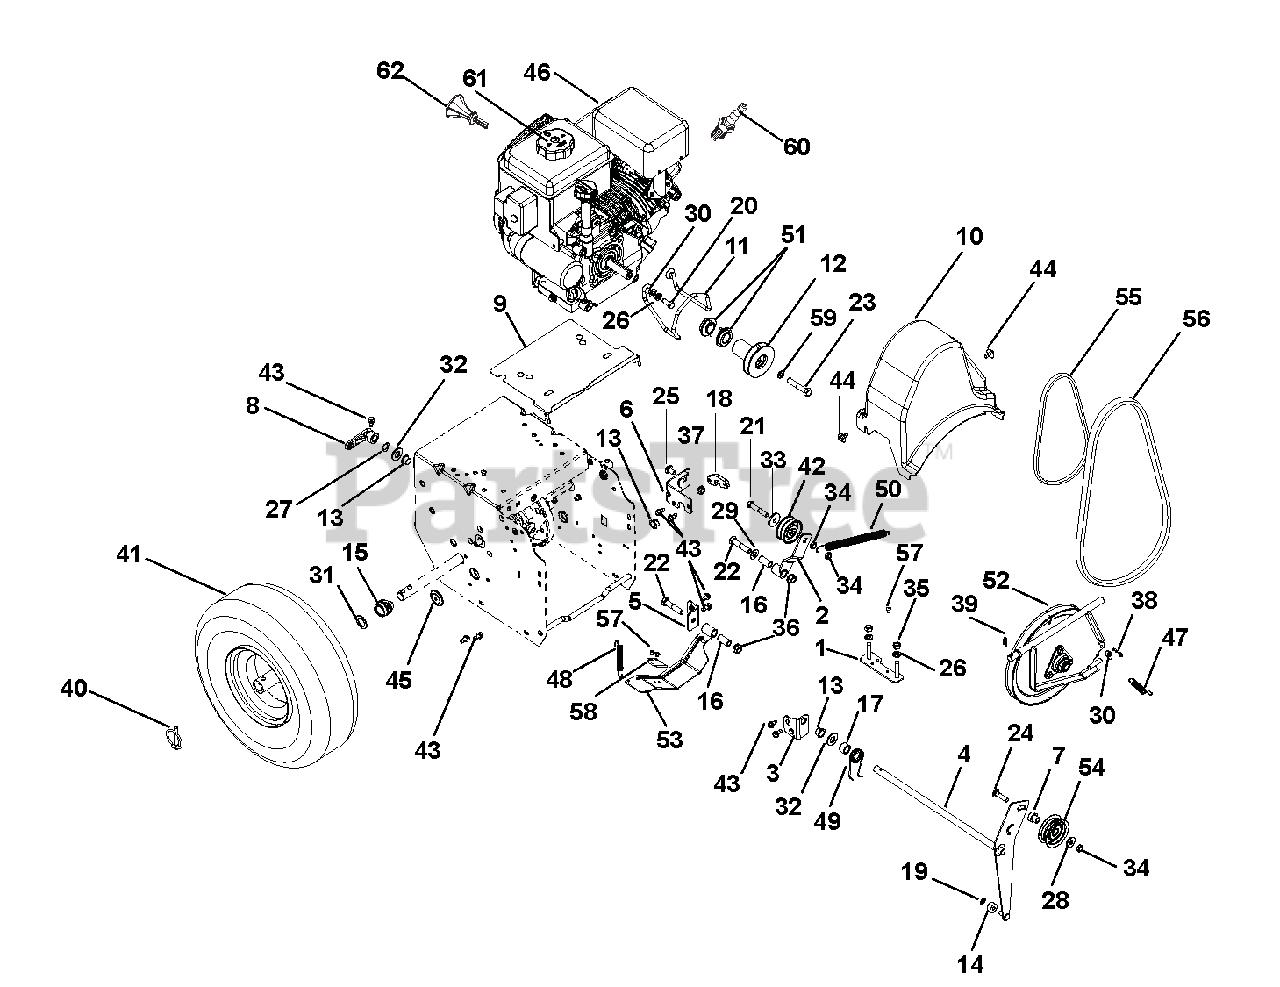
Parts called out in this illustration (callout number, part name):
1	STRAP, ENGINE BOLT-WELDMENT
2	WELDMENT, TRACTION IDLER ARM
3	BRACKET, MOUNT - IDLER ARM
4	WELDMENT, ATTACHMENT IDLER ARM
5	BRACKET, MOUNT - BRAKE
6	WELDMENT, FRAME BRACKET
7	SPCR, BRG .315X.50X.688X.281
8	ARM, CLUTCH - ATTACHMENT
9	BAFFLE,ENGINE,SMALL BLOCK
10	COVER, COMPACT BELT
11	FINGER, BELT
11	BELT FINGER
12	SHEAVE, AUGER - COMPACT
12	SHEAVE, ATTACHMENT DRIVE
13	BUSHING, POLYLINER-.50 SPLIT
14	BSHG,SLV .265 X .625 X .375
15	BSHG .75X1.125X.65
16	BSHG-SLV .385X.500X1.045
17	BSHG-SLV .510X.751X.475
18	SPACER, SWING GATE
19	RG-RTNG-EXT .250X.010
20	BLT-HEX .31-24X.75 YWZC GR5
21	@BLT-HEX .31-18X1.75 GR5 YWZC
22	@BLT-HEX .38-16X1.75 GR5 YWZC
23	BLT-HEX .38-24X2.0 YWZC
24	BLT-RDHDSQSHNK.31-18X1.13 G5YZ
25	@BLT-RHDSSQNK .31-18X.62 G5YZ
26	WSHR-LK .312X.097 HVY YWZC
27	WSHR-WAVE .50X.75X.015 .13FRHT
28	@WSHR-FL-STL.38X.875X.083 YWZC
29	@WSHR-FL-STL.406X.812X.065 YWZ
30	@WSHR-FL-STL.344X.688X.065YWZC
31	WSHR-FL-STL.754X1.125X.062YWZC
31	BSHG-SLV .75X1.12X1.062 NYL BK
32	@WSHR-FL-STL.531X1.06X.095YWZC
33	WSHR-FL-STL .344X1.125X.135
34	@NUT-LK-CTR-JAM .31-18 YWZC
35	@NUT-HEX .31-18 YWZC
36	@NUT-LK-TOP-FLG .38-16 YWZC
37	@NUT-LK-TOP-FLG .31-18 YWZC
38	PIN-HAIR INT .08X.18X1.18 YWZC
39	CLIP, SPRING
40	PIN-LOK .31X1.75
41	TIRE/WHEEL, 15X5.00-6 K398A
41	TIRE/WHEEL, 13X4.10-6 K398A
41	TIRE, 13" K398A
41	TIRE, 15" K398A
42	IDLER,1.875" OD
43	SCR-TAP .25-20X.50 HWH TR YWZ
44	SCR-TAP .25-20X.50 LGHWH TR YZ
45	PLUG, HOLE - 1.00" FLEXTEMP
46	ENGINE,LCT STORMFORCE 208 120V
46	ENGINE,LCT STORMFORCE 136 120V
47	SPRING, EXT. .043X.438X1.64
48	SPRING-EXT .437 X .438 X 2.64
49	SG-TORS .075 X .955
50	SPRING, EXTENSION
51	TRACTION SHEAVE HALF
52	PLATE, SWING - ASSEMBLY
53	BRAKE ARM W/PAD
54	IDLER
55	V-BELT, 3L-WRAPPED
56	V-BELT, HA-RAW EDGE
57	RVT-POP .187 YZ
58	PAD, BRAKE
59	@WSHR-LK .38X.094 REG YWZC
60	PLUG, SPARK
61	CAP, FUEL TANK BLACK
62	KEY, PUSH/PULL LCT (2/PACKAGE)
